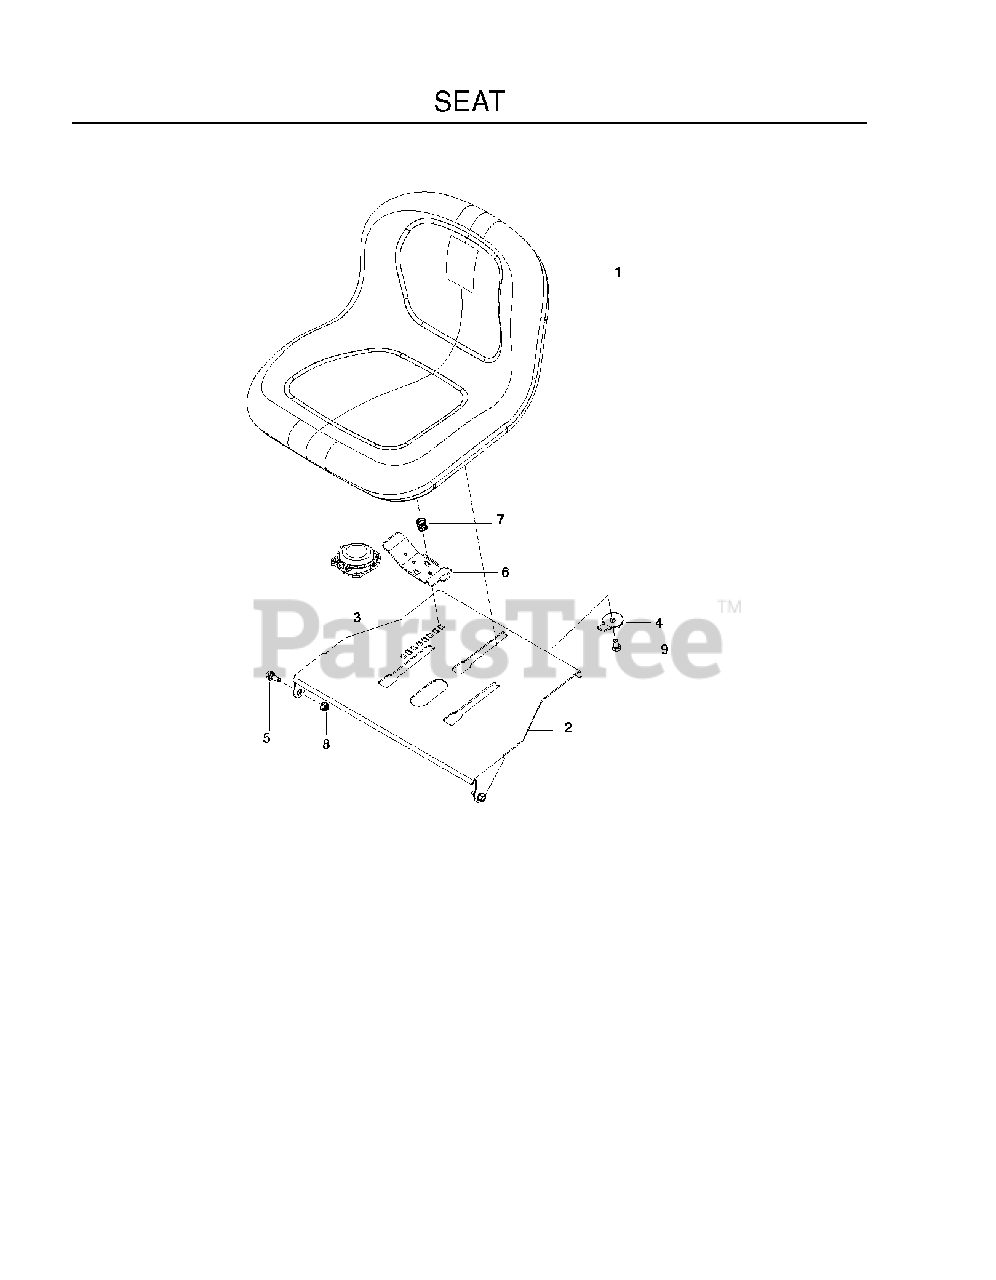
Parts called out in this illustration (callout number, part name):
1	Seat, Th150.Ms498.Gry.Husq.Tex
2	PLATE, SEAT, BLUE
3	SWITCH, SEAT N/C
4	STOP, SEAT, BLACK
5	BOLT, SHOULDER
6	HANDLE.SLIDE.SEAT.TEX.BLACK
7	SPRING.LATCH.SEAT.TEX
8	5/16-18 NYLOC FLANGE NUT
9	HCS 3/8-16 X 5/8 GR 5 ZD
